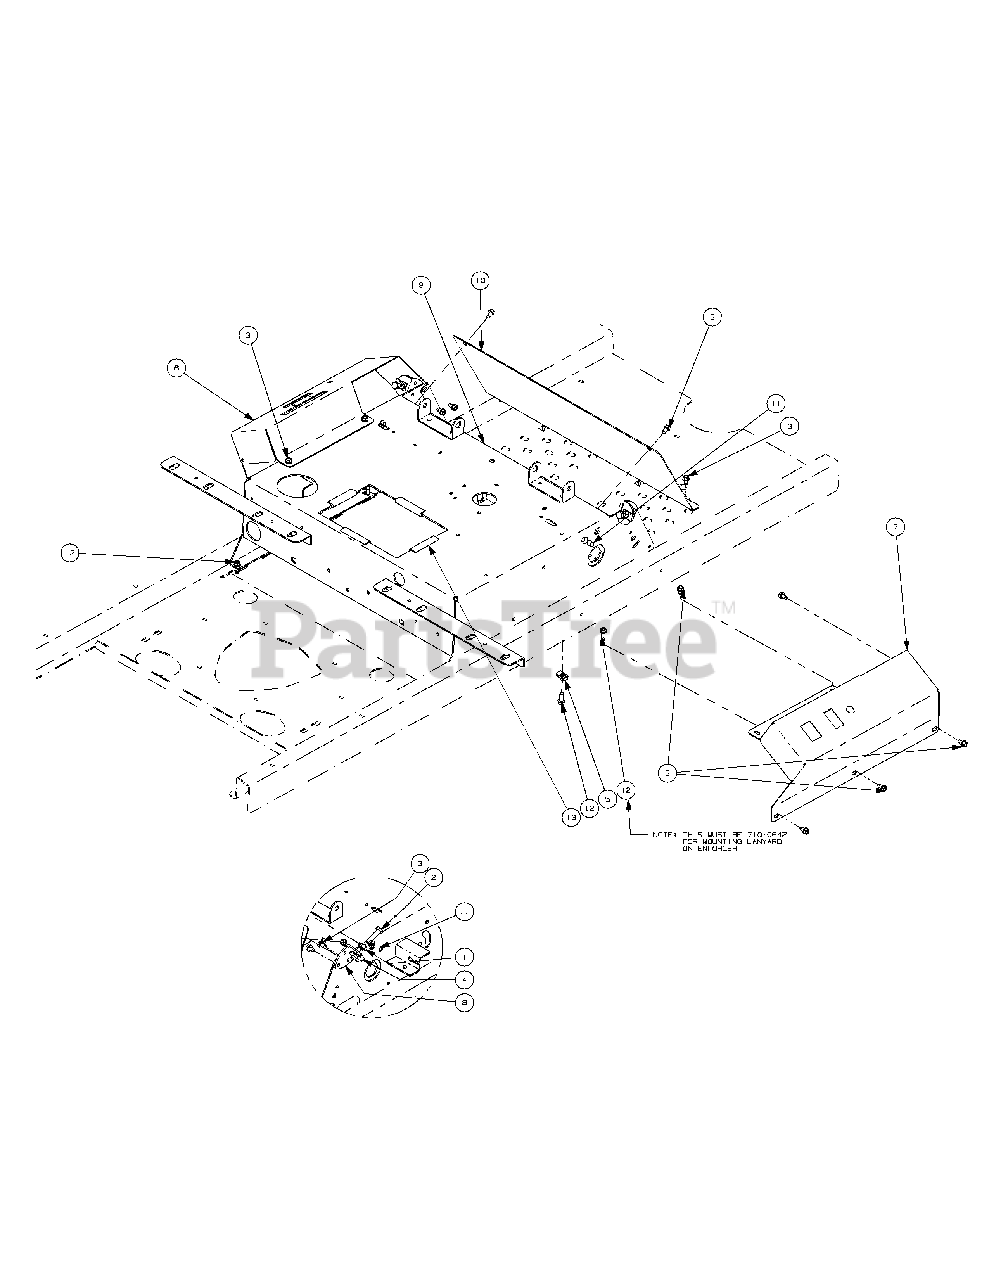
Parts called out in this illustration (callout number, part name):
1	Hex Nut, 5/16-18
2	HHCS, 5/16-18 x 1-1/4
3	Screw, 1/4-20 x 1/2
4	U-Nut, 5/16-18
5	U-Nut, 1/4-20
11	Self Tapping Screw 5/16-18 x .750
12	Self Tapping Screw, 1/4-20 x .75
13	Battery Edge Trim
